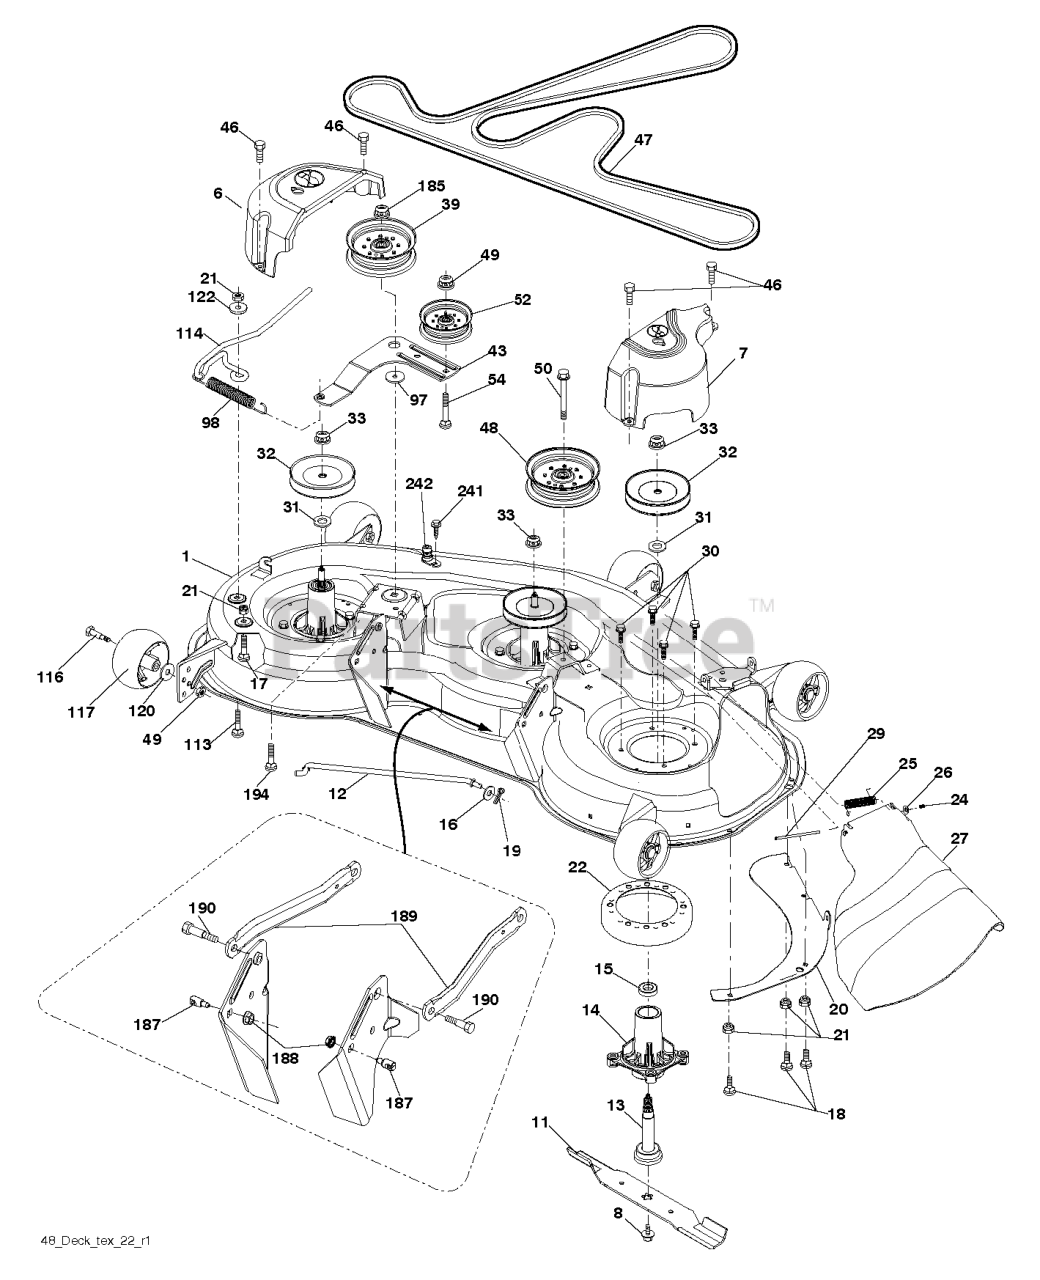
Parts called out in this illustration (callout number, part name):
1	DECK.PNT.WELDMENT.48"TEX.498
6	COVER.MANDREL.LH.48"(2 2)
7	COVER.MANDREL.RH.48"
8	BOLT.WASHER.ASM.7/16-2
11	48" HI-LIFT BLADE
12	ROD.ANTI.SWAY.48/54"TE
13	SHAFT ASM MANDREL
14	RP.HOUSING.MANDREL.4PT.
16	WASHER
17	BOLT.CARR.5/16-18X5/8.SHORT
18	BOLT
19	PIN.COTTER.5/16.BOW TI
20	BAFFLE, VORTEX MWR
21	LOCKNUT
22	STRIPPER.MANDREL.ROUND.BLACK
24	CAP-SLEEVE LT
25	SPRING, TORSION
26	NUT PUSH M
27	DEFLECTOR SUBS TO 532 180655
29	ROD.HINGE
30	SCREW, WASHER HEAD
31	WASHER.SPACER.MANDREL
32	PULLEY/MANDREL
33	NUT.FLANGE.LOCK.TOP
39	RB PULLEY.IDLER.4.50/HUB SPEC
43	ARM.IDLER
46	SCREW.1/4-20X5/8
47	BELT.DRIVE.DECK
48	PULLEY.IDLER.2006
49	NUT LOCK FLG 3/8-16 UNC
50	SCREW TT 3/8-16X2-1/4 UNC
52	PULLEY.IDLER.2006
54	BOLT.3/8-16X1.50
98	SPRING, DECK DRIVE
113	BOLT CRT
114	ROD.TENSION.RELIEF.TEX (2 2)
116	BOLT.SHOULDER.3/8-16X3-5/8.
117	RP WHEEL. GUAGE RALLY
120	WASHER
122	BUSHING.RELIEF.TENSION
185	NUT.LOCK.FLANGE.7/16
187	STUD.FASTNER.W/ANTI-ROTATE
188	NUT LOCK HEX FLANGE 5/16-18
189	ARM.SUSPENSION.MOWER
190	BOLT.SHOULDER
194	BOLT.HEX.WASHER.HEAD.7/16-24X
241	SCREW.TT.#10-32X.5.3/8.FLANGE
242	PORT.WASHOUT
